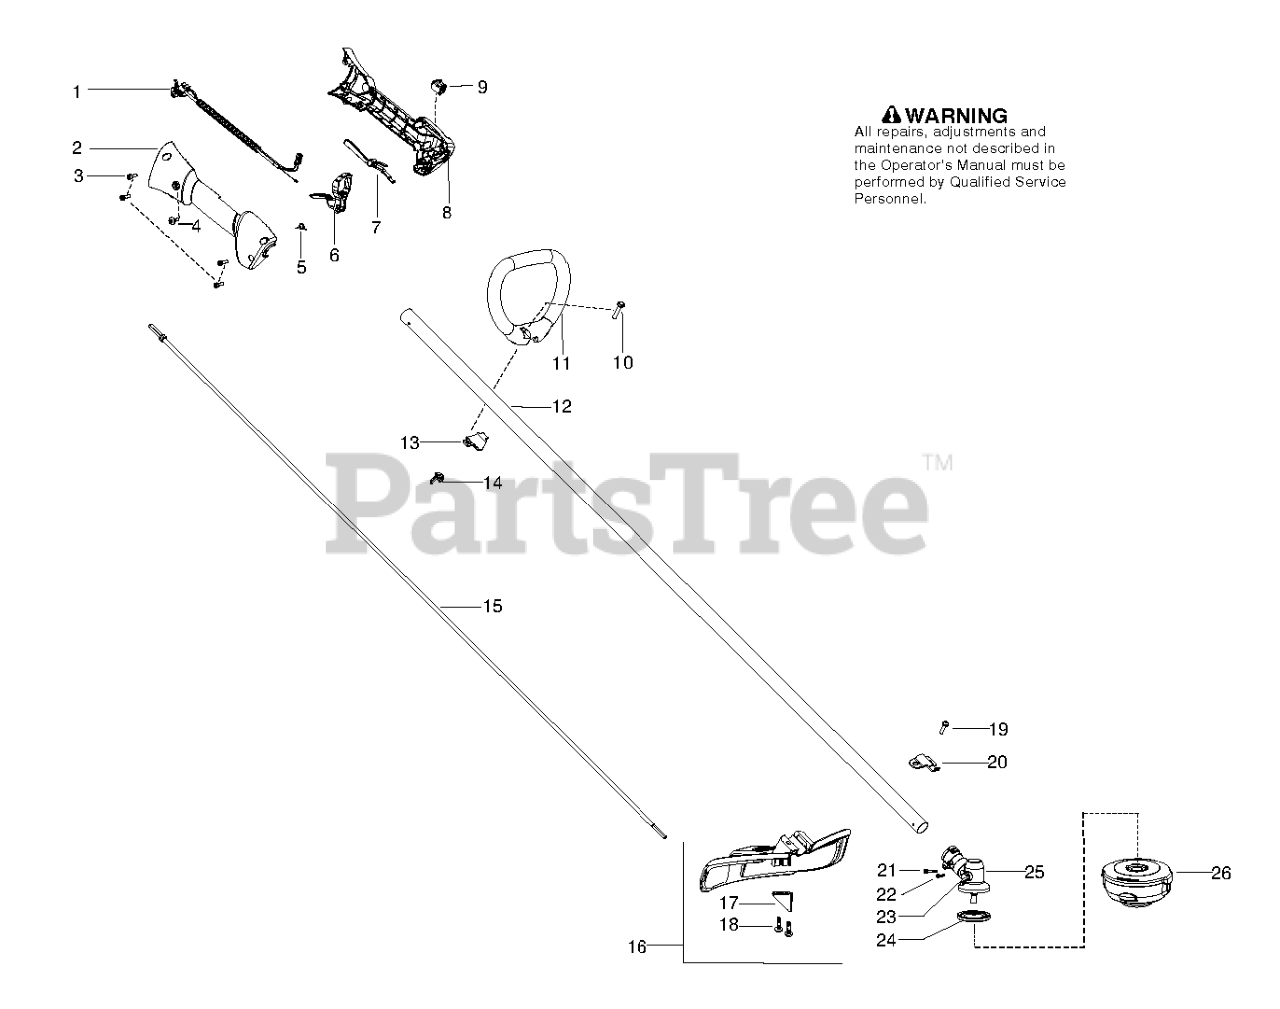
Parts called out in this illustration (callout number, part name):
1	ASSY CABLE / WIRE HARNESS
2	HSG THROTTLE RIGHT HVA
3	SCREW M4 X 1.75 PT 16MM
4	SCREW-10-14 X 1/2 PLASTITE
5	SPRING TRIGGER
6	TRIGGER THROTTLE HVA ORANGE
7	THROTTLE LOCKOUT HVA ORANGE
8	HSG THROTTLE LEFT HVA
9	SWITCH
10	BOLT, TYPE 2
12	KIT DRIVE SHAFT SST US / CAN
13	CLAMP ASSIST HANDLE
14	WINGNUT, TYPE 2
15	FLEXSHAFT 57"
16	KIT COBI SHIELD
17	Limiter - Line
19	SCREW 1/4-20 X 7/8 (TAP
20	BRACKET SHIELD STRAIGHT SHAFT
21	SCREW - CARB. ADAPTOR
23	PLUG GREASE 9MM
24	DRIVE DISC
25	ASSY GEARBOX
26	T25 TRIM HEAD 10MM LH
